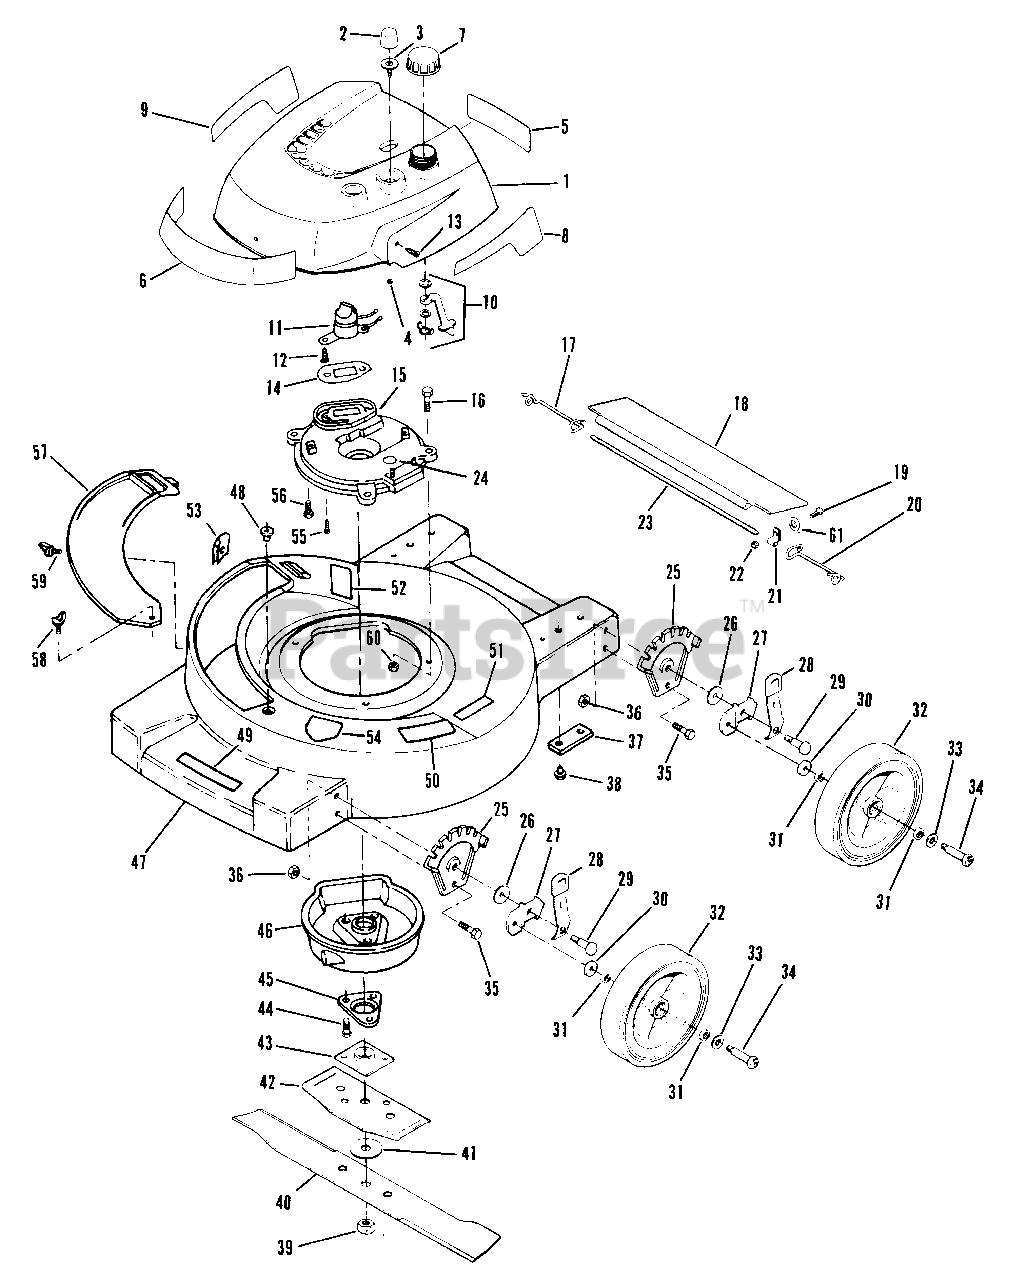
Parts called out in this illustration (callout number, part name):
1	Shroud-Engine
2	Bulb-Primer
3	Base-Primer
4	Nut
5	Decal-Instructions
6	Decal-Lawn-Boy
7	Fuel Cap
8	Decal-L.H.
9	Decal-R.H.
10	Fuel Shut-Off Assembly
11	Switch-On-Off
12	Screw
13	Screw-Shroud Mounting
14	Gasket-Exhaust
15	Plate-Muffler
16	Screw-Muffler Plate to Housing
17	Spring-R.H.
18	Shield-Trailing 21"
19	Screw
20	Spring-L.H.
21	Clamp
22	Nut
23	Rod-Trailing Shield 21"
24	Pushnut-Model Plate Mtg
25	Plate-Height Adjust
26	Washer
27	Bracket-Wheel Height Adjustment
28	Knob & Spring Assembly
29	Shoulder Bolt
30	Washer
31	Washer-Felt
32	Wheel
33	Washer
34	Bolt-Wheel
35	Screw-Plate Height Adjustment
36	Nut-Back-Up Plate & Adjustment Bracket
37	Plate-Handle Bracket Screw
38	Screw-Handle Bracket to Housing
39	Nut-Blade
40	Blade-21"
41	Washer-Blade
42	Stiffener-Blade
43	Collar & Plate Assembly
44	Screw
45	Support-Crankshaft
46	Muffler Cover Assembly
47	Housing-21"
48	Grommet
49	Decal-Caution
50	Pad-Starting
51	Decal-Starting Pad
52	Decal-Discharge Area
53	Speed Nut-Cover Mounting
54	Decal-Blade Contact Warning
55	Screw-Muffler Plate to Block
56	Screw-Muffler Plate to Block
57	Cover Plate
58	Wing Screw
59	Thumb Screw-Cover Plate-Side
60	Nut-Muffler Plate to Housing
61	Washer
